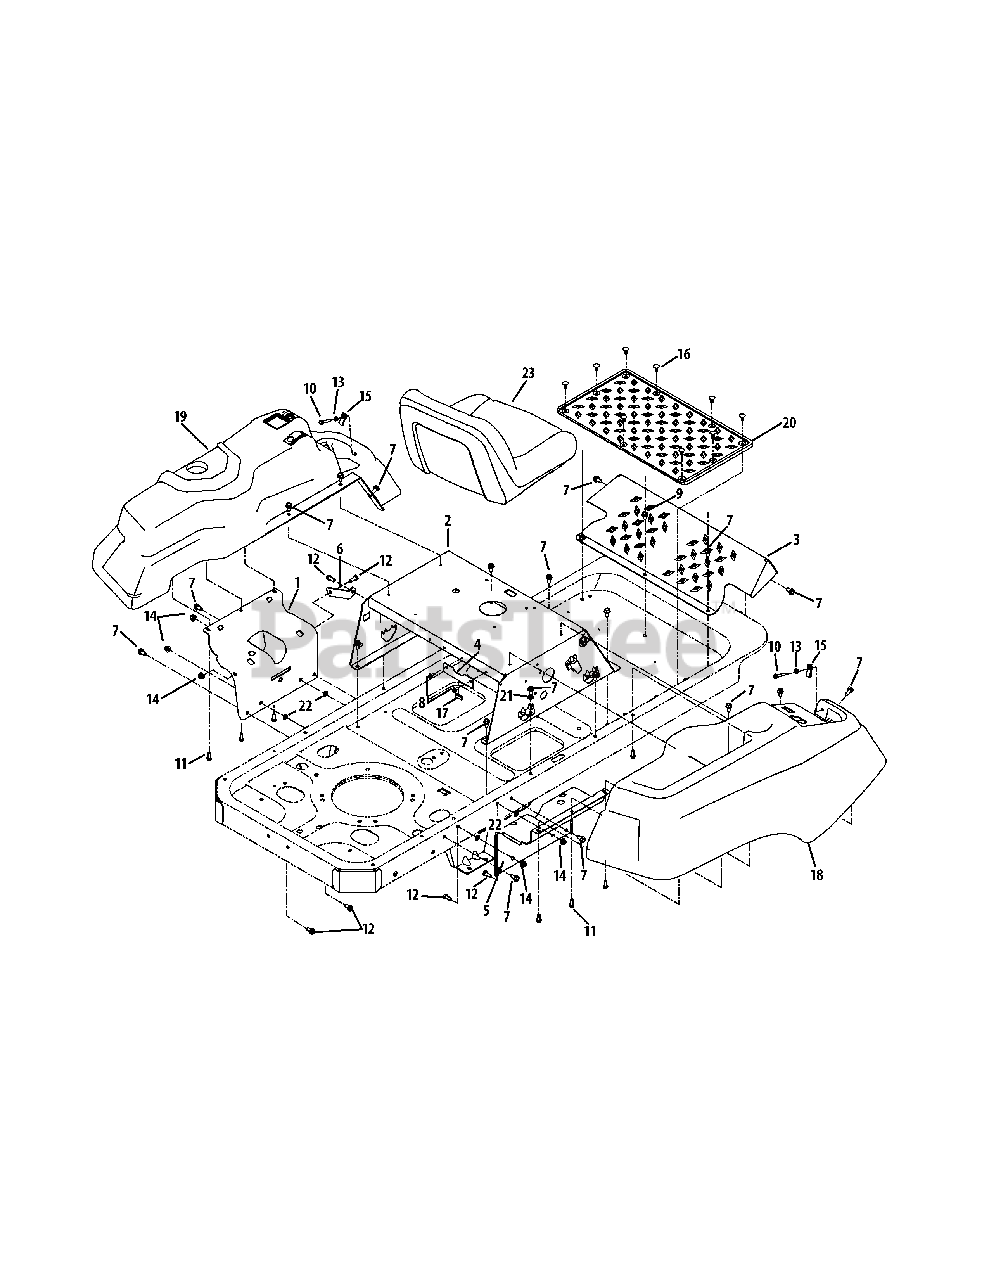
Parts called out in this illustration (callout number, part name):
1	Console Bracket Assembly
2	Seat Frame Assembly (NLA) - Black Jack
2	Seat Frame Assembly - Black Jack
3	Foot Rest Bracket
4	Battery Hold-Down Bracket
5	Console Mount Bracket
6	Fuel Tank Support Bracket
7	Hex Washer Screw, 5/16-18 x .750
8	Hex Washer Screw, 1/4-20 x .500
9	Hex Washer Screw, 5/16-18 x .625
10	Hex Washer Screw, 1/4-20 x 1.500
11	Hex Washer Screw, 1/4-15 x .750
12	Hex Screw, 5/16-18 x .75
13	Jam Nut, 1/4-20
14	Flange Lock Nut, 5/16-18
15	Speed Nut, 1/4-20
16	Ratchet Clip
17	Trim Strip
18	RH Console (Black)
18	RH Console (Oyster Gray)
19	LH Console (Black)
19	LH Console (Oyster Gray)
20	Foot Pad
21	Lock Washer, 3/8
22	Speed Nut, .3125
23	High-Back Seat Arm
